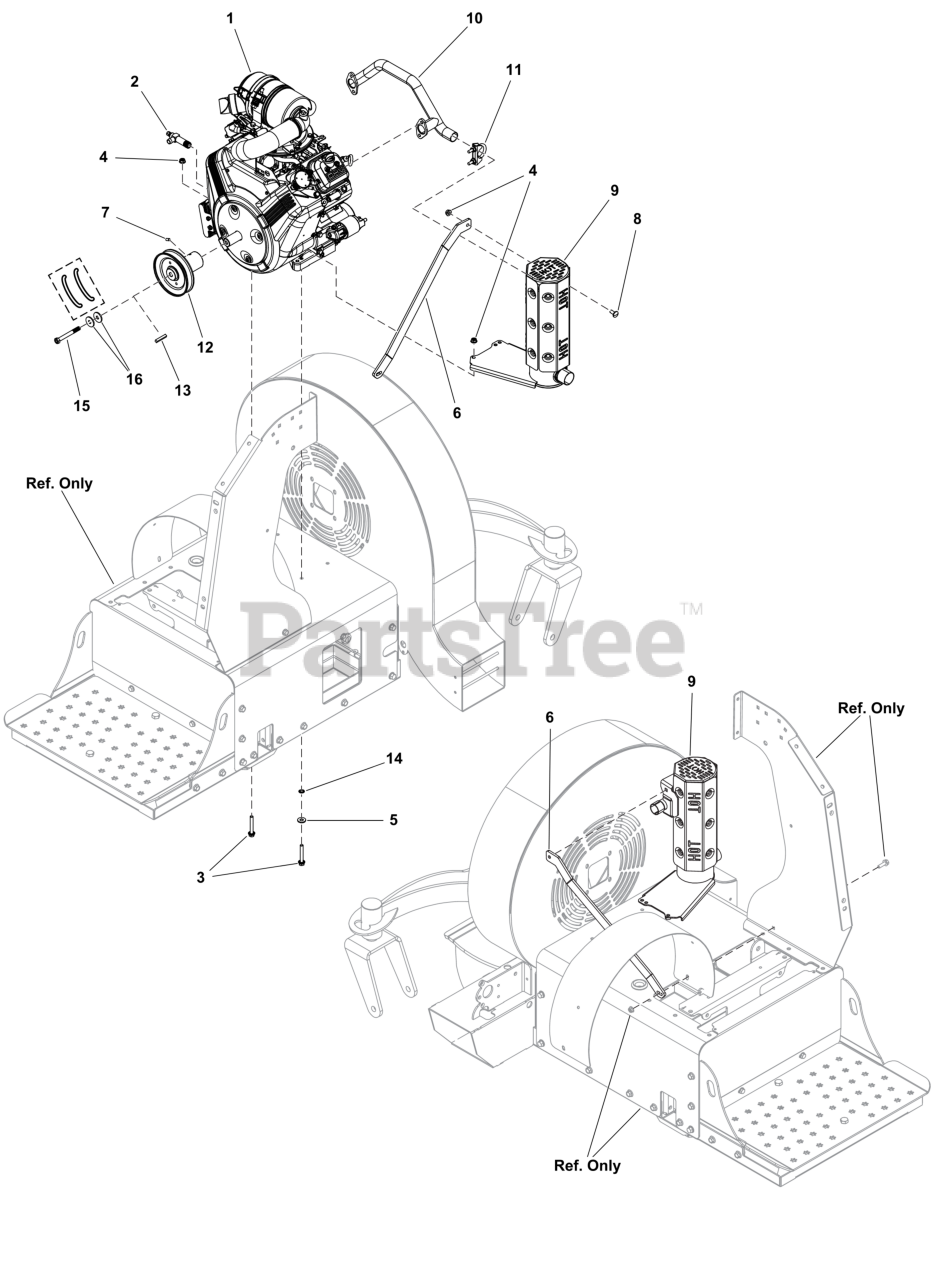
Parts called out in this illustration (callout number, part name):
2	VALVE, OIL DRAIN SHUT OFF
4	NUT, 5/16-18 HEX SERR
7	SET SCREW
8	BOLT, Round Head, Short Square Neck
9	KIT, Muffler
10	MANIFOLD
11	CLAMP, MUFFLER
13	KEY 1/4 SQ X 1 1/2
14	WASHER, 5/16" INT. TO
15	BOLT, 3/8-24 NF x 3-1/4" Hex Head, GR 8
16	WASHER, Beveled
